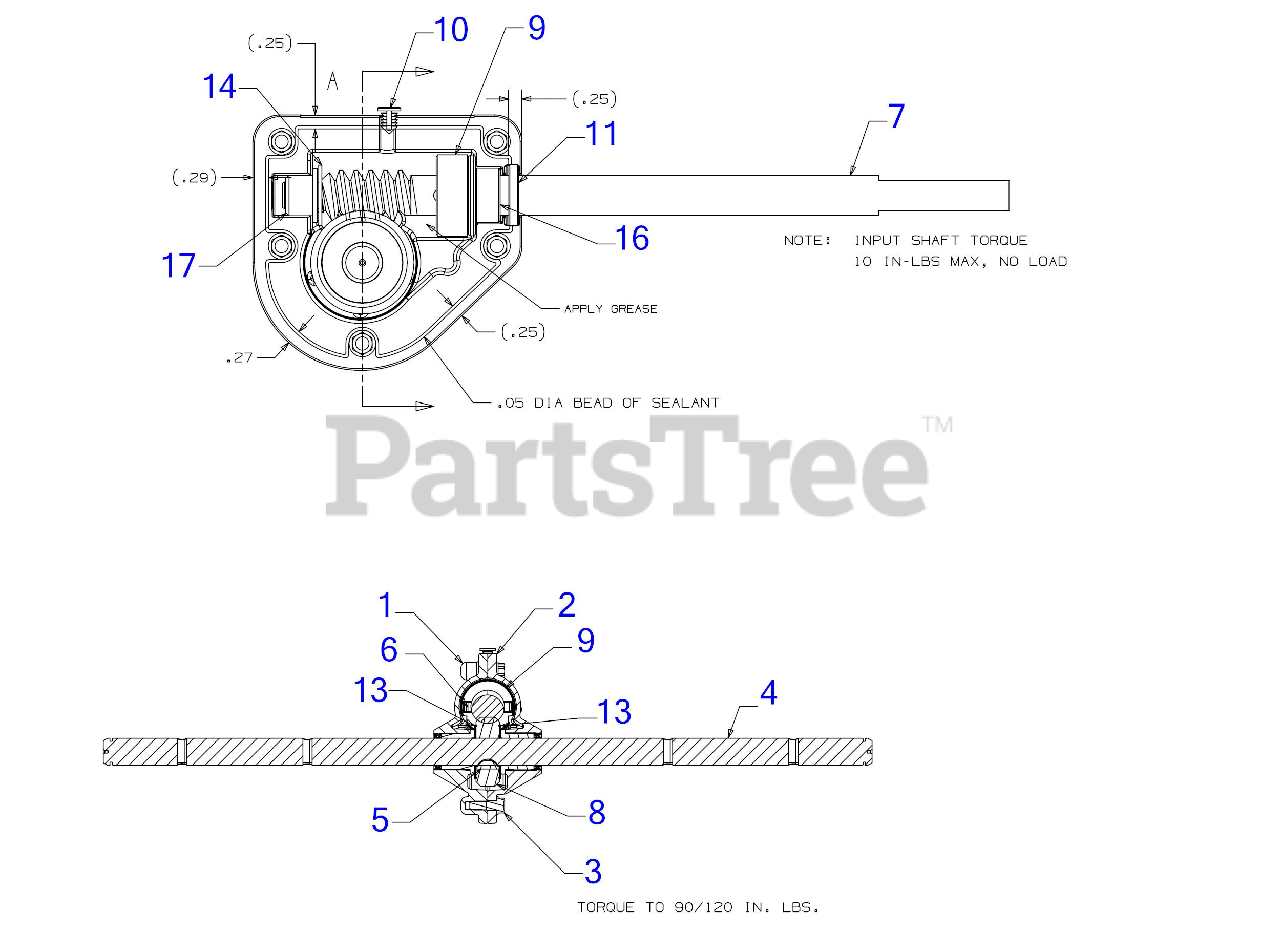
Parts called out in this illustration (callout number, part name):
1	REDUCER HOUSING ASSEMBLY (RH)
2	REDUCER HOUSING ASSEMBLY (LH)
3	SCREW 1/4-20 x .750
4	22" AUGER SHAFT
5	KEY 3/16 x 5/8 H
6	DOWEL PIN
7	WORM SHAFT
8	WORM GEAR 20T
9	COLLAR-THRUST .756ID x .600
11	OIL SEAL .75 x 1.131 x .188
13	THRUST WASHER
14	FLAT WASHER
16	FLANGE BEARING
17	FLANGE BEARING
